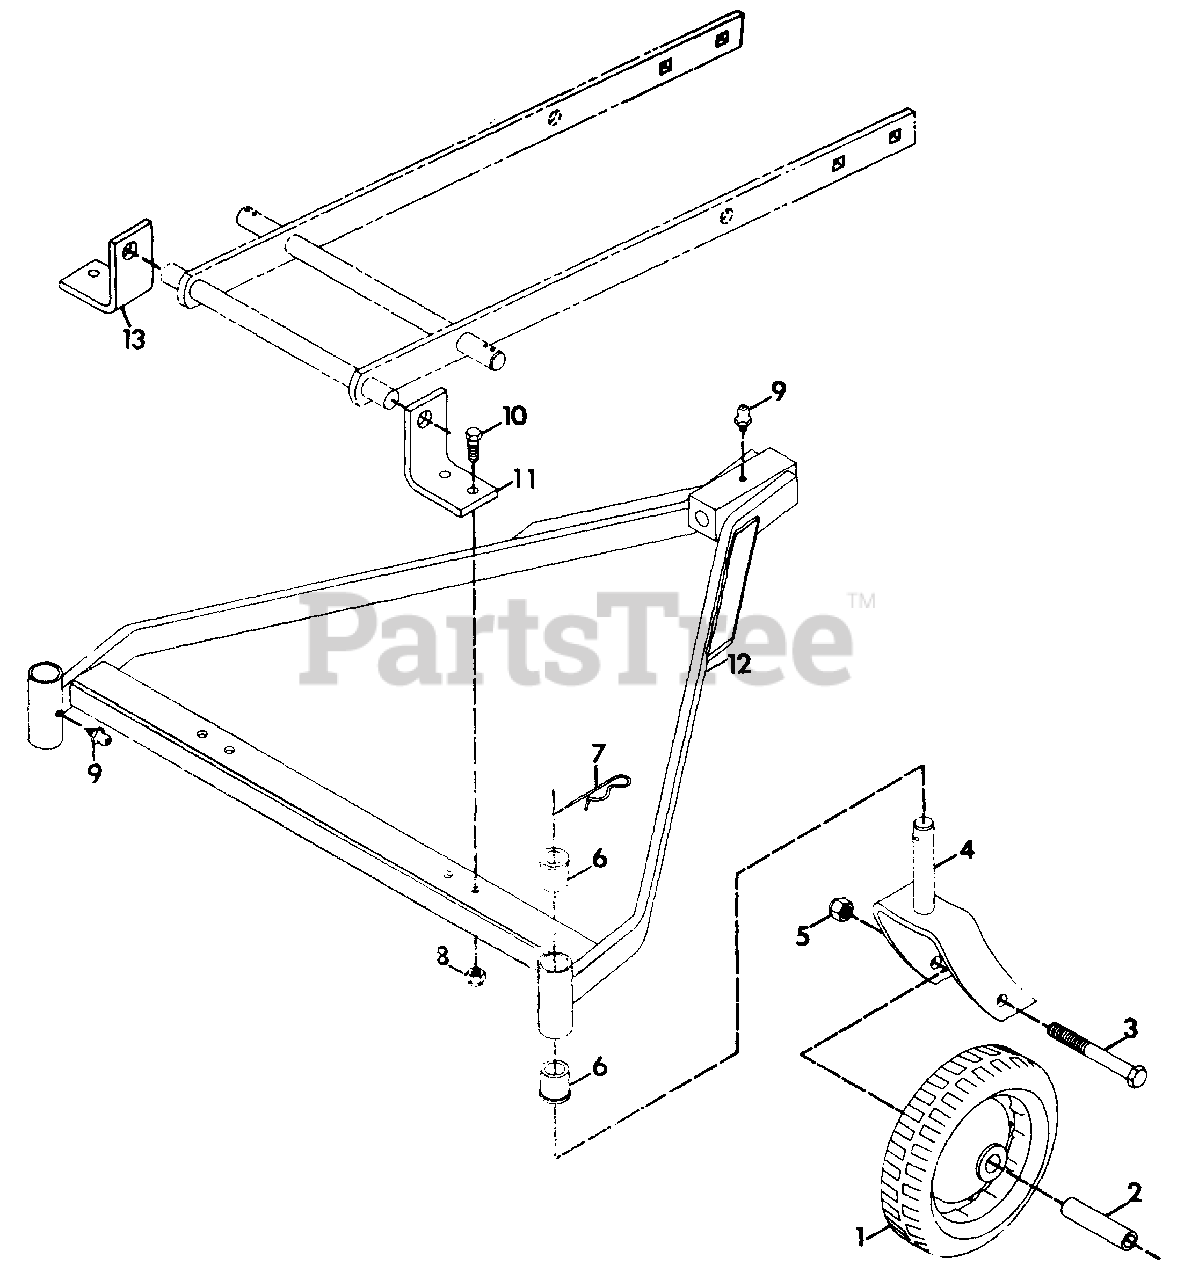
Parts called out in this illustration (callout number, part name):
1	WHEEL, GAUGE
2	BUSHING, WHEEL; .520
3	BOLT, HEX 1/2-13X5
4	WELDMENT, CASTER FORK
5	NUT, LOCK 1/2-13 WASHER
6	BUSHING .725X1.065
7	PIN, HAIR
8	NUT, LOCK 3/8-16 WASHER INSERT
9	FITTING, LUBE 1/4-28
10	BOLT, HEX 3/8-16X1.25
11	SUPPORT, PIVOT ARM L.H.
12	ASSEMBLY, FRAME WELDMENT
13	SUPPORT, PIVOT ARM R.H.
